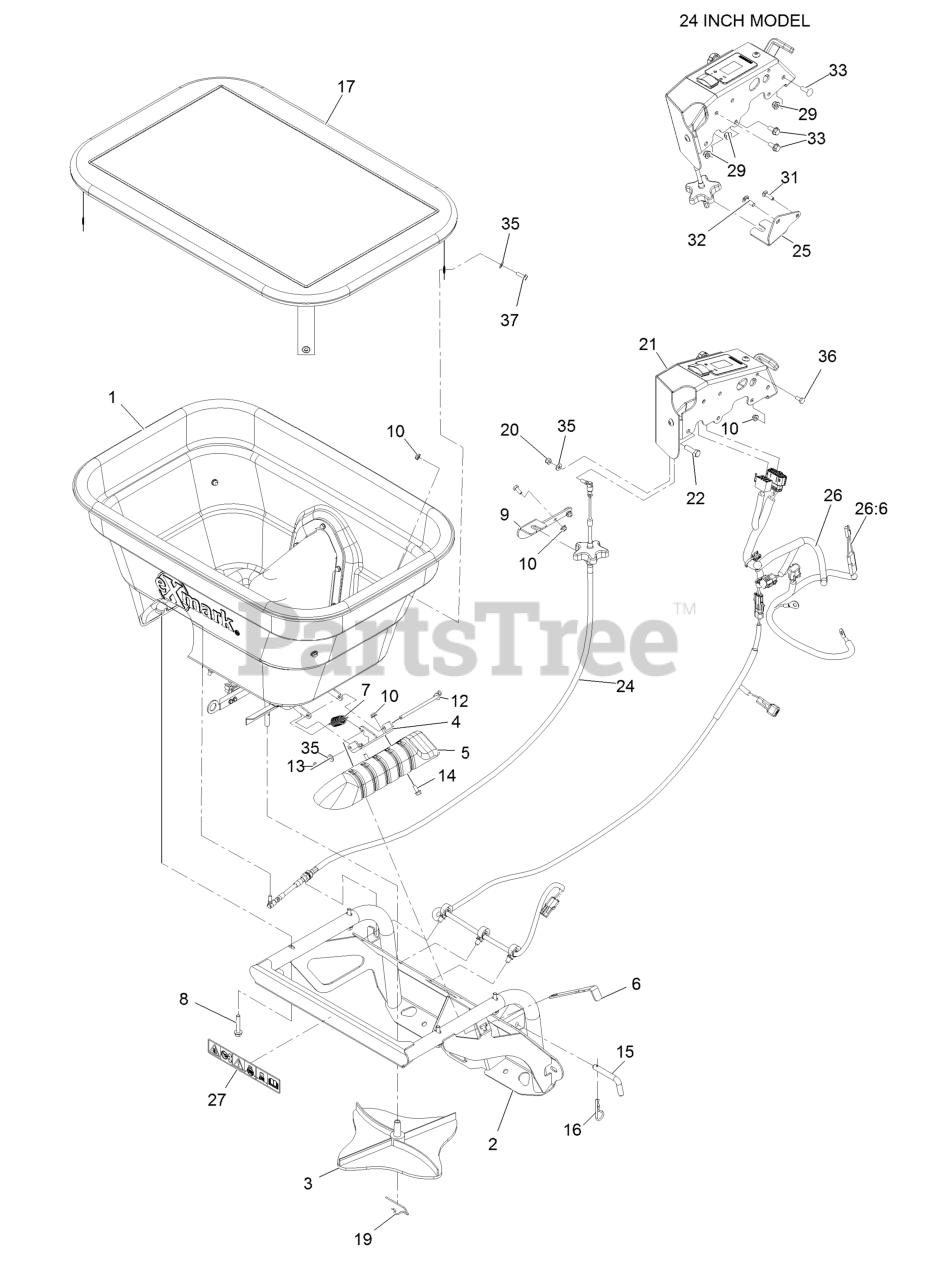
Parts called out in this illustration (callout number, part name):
1	Asy-Spreader Hopper (Exmark)
2	Spreader Hopper Frame ASM
3	Spinner-Spreader
4	Bracket-Deflector
5	Deflector
6	Strap-Engagement
7	Spring-Extension
8	Screw-HWH
9	Bracket-Cable
10	Nut-Nyloc 1/4-20 Flg
12	Pin-Pivot
13	Hairpin-Cotter
14	Screw-Head, Flange
15	Pin-Hitch
16	Pin-Hair
17	Cover-Hopper
19	Clip-Spinner
20	Nut-Nyloc 1/4-28
21	Spreader Controller ASM
22	Screw-HH 3/8-16 X 1 1/4
24	Cable-Push, Pull
25	Bracket-Cable
26	Harness
26:6	Connector
27	Decal-Down, Tie
29	Nut-Nyloc 5/16-18 Flg
31	Bolt-Carriage 1/4-20 X 1
32	Bolt-Carriage 5/16-18 X 1 Sp
33	Screw-HH Flg 5/16-18 X 3/4
35	Washer-1/4 SAE
36	Screw-HH 1/4-20 X 5/8
37	Screw-Machine 1/4-20 X 3/4
